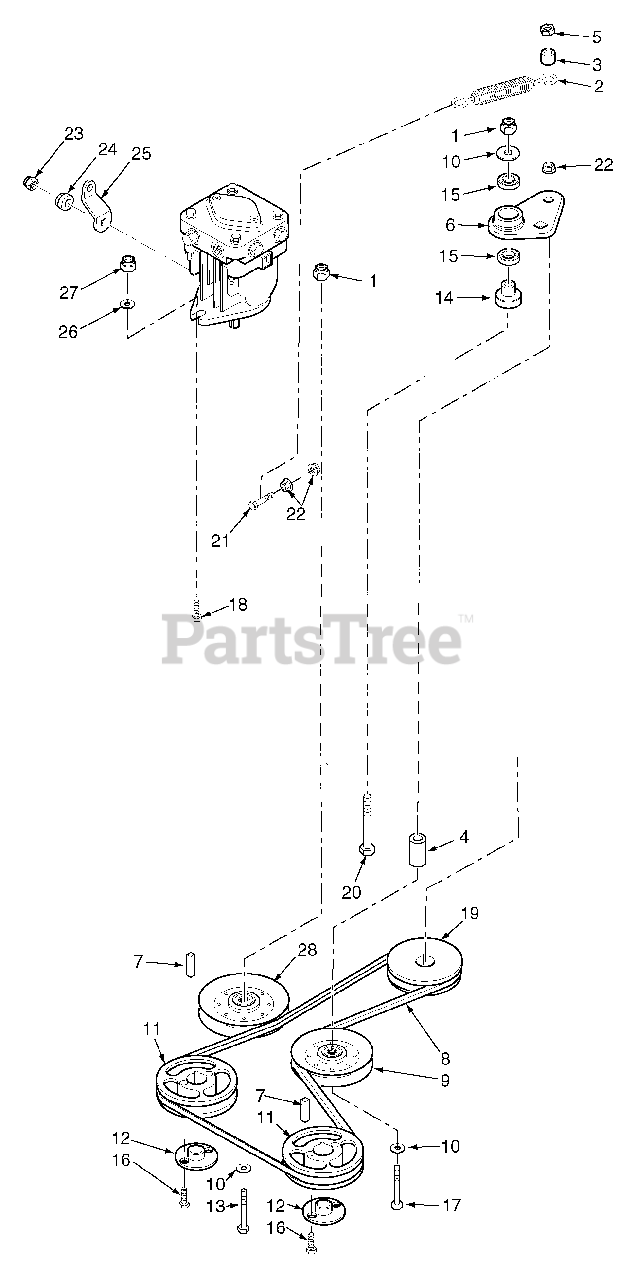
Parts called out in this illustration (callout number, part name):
1	Nut, Elastic Stop 3/8-16
2	Spring, SZC Pump Drive
3	Sleeve
4	Spacer, Pump Idler
5	Nut, Center Lock 3/8-16
6	Idler Arm Assembly, Pump Drive
7	Key, 5 x 5 x 25mm
8	Belt, Pump Drive SZC
9	Pulley, Idler 3" Dia.
10	Flatwasher, 3/8-.391 x .938 x .105 HD
11	Pulley, 5.45 O.D. Tapered Bore
12	Hub, Tapered, 15mm Bore
13	Bolt, Hex Head 3/8-16 x 2"
14	Pivot, Idler Short
15	Bearing
16	Bolt, Hex Head 1/4-20 x 1" Grade 8 Black
17	Bolt, Hex Head 3/8-16 x 3-1/4"
18	Bolt, Hex Head 3/8-16 x 1-1/2"
19	Pulley, 5.45" Dia. 1" Bore
20	Bolt, Hex Head 3/8-16 x 2-1/2"
21	Bolt, Hex Head 3/8-16 x 1-1/4 Grade 8 Black
22	Nut, Serr. Flange 3/8-16
23	Nut, Center Lock 5/16-24
24	Retainer, Pump Lever
25	Control Lever, Pump
26	Flatwasher, 3/8-.391 x .938 x .105
27	Nut, Elastic Stop 3/8-16
28	Pulley, Idler
